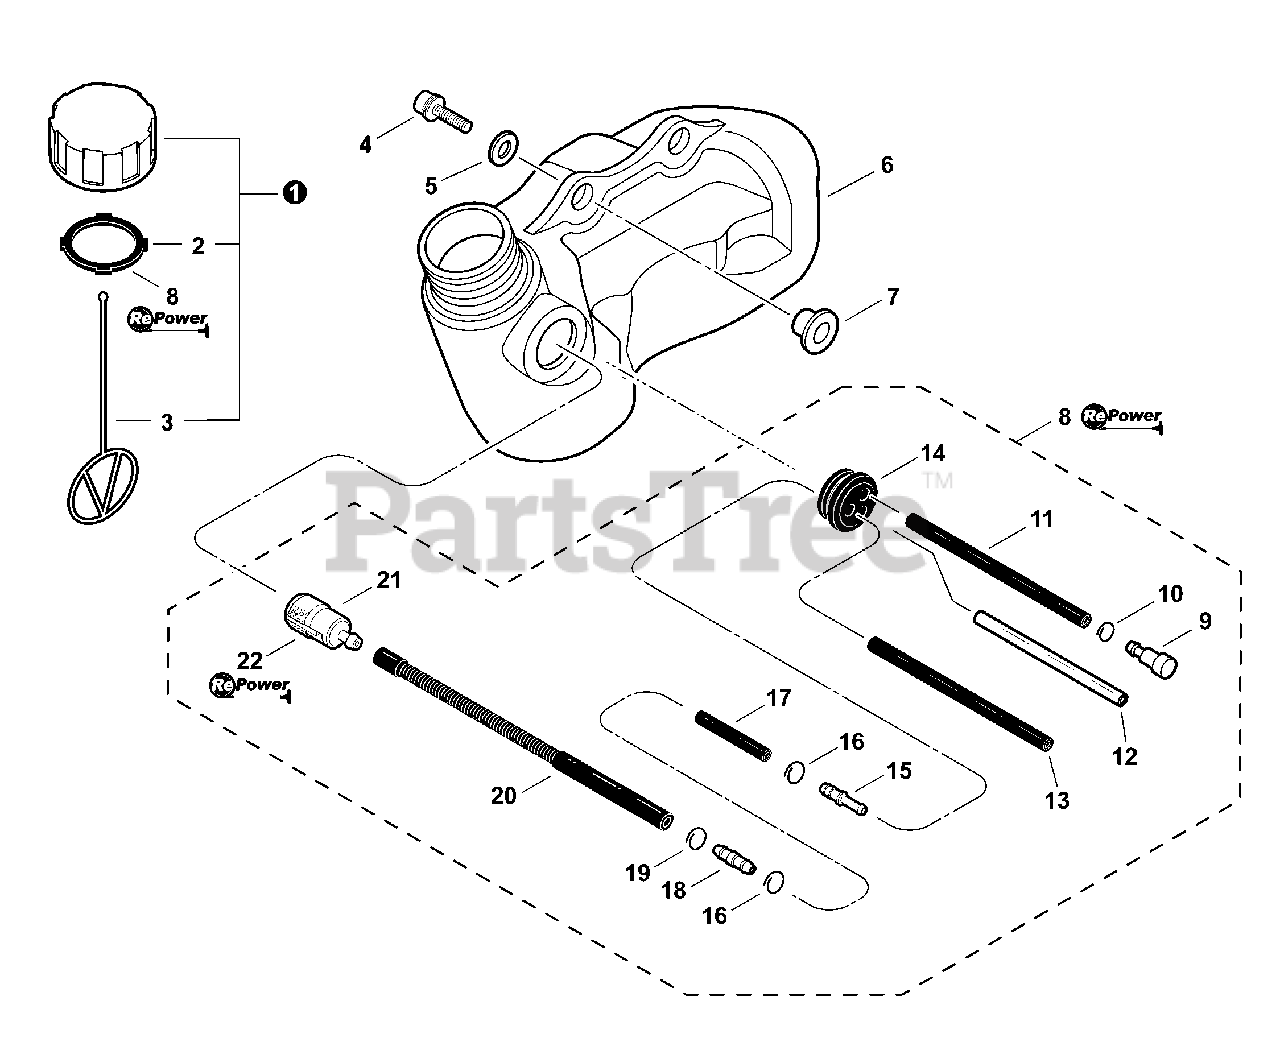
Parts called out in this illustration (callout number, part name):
1	CAP ASSY, FUEL
2	GASKET, FUEL CAP
3	CONNECTOR, CAP L= 123
4	BOLT 5×20
5	WASHER 5.5×12×0.8
6	TANK, FUEL
7	COLLAR 5
8	FUEL SYSTEM KIT
9	VENT ASSY
10	CLIP Ø6
11	PIPE, FUEL 3×6×50 BLACK
12	PIPE, FUEL 3×6×75 CLEAR
13	PIPE, FUEL 3×5×61 BLACK
14	GROMMET, FUEL
15	CONNECTOR, PIPE Ø5ר3.5
16	CLIP Ø6.5 MM
17	PIPE, FUEL 3×6×35 BLACK
18	CONNECTOR, PIPE
19	CLIP 6.6 MM
20	PIPE, FUEL 3×7×100 FLEXIBLE
21	FILTER, FUEL
22	FILTER KIT - REPOWER
22	TUNE-UP KIT - REPOWER
